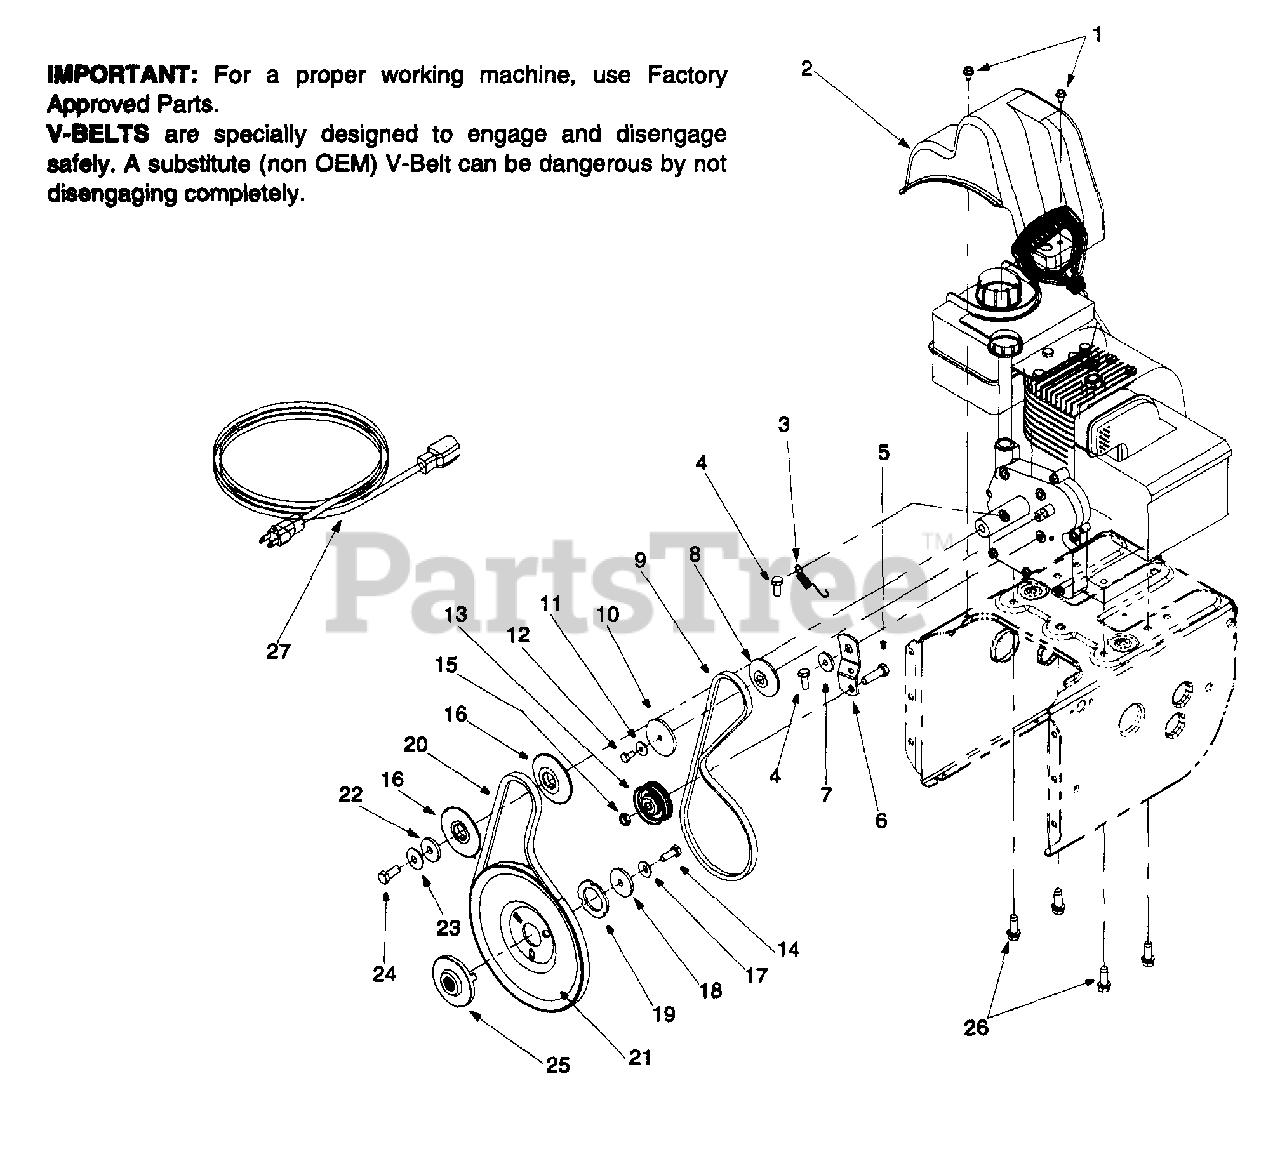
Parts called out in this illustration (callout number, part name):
1	Hex Washer Screw 1/4-20 x.5
2	Belt Cover
3	Extension Spring
4	Hex Screw 5/16-24 x .75
5	Hex Cap Screw 3/8-16 x 1.25
6	Drive Clutch Bracket
7	Shoulder Spacer
8	Pulley Half
9	V-Belt
10	Pulley Half
11	Bell Washer
12	Hex Cap Screw 1/4-28 x .50
13	Flat Idler
14	Lock Cap Screw 5/16-24
15	Lock Jam Nut 3/8-16
16	Pulley Half
17	Bell Washer
18	Flat Washer
19	Washer
20	Belt
21	Auger Pulley
22	Flat Washer
23	Bell Washer
24	Hex Cap Screw 3/8-24
25	Pulley
26	Hex Washer Screw 3/8-16 x 1.0
27	Extension Cord
